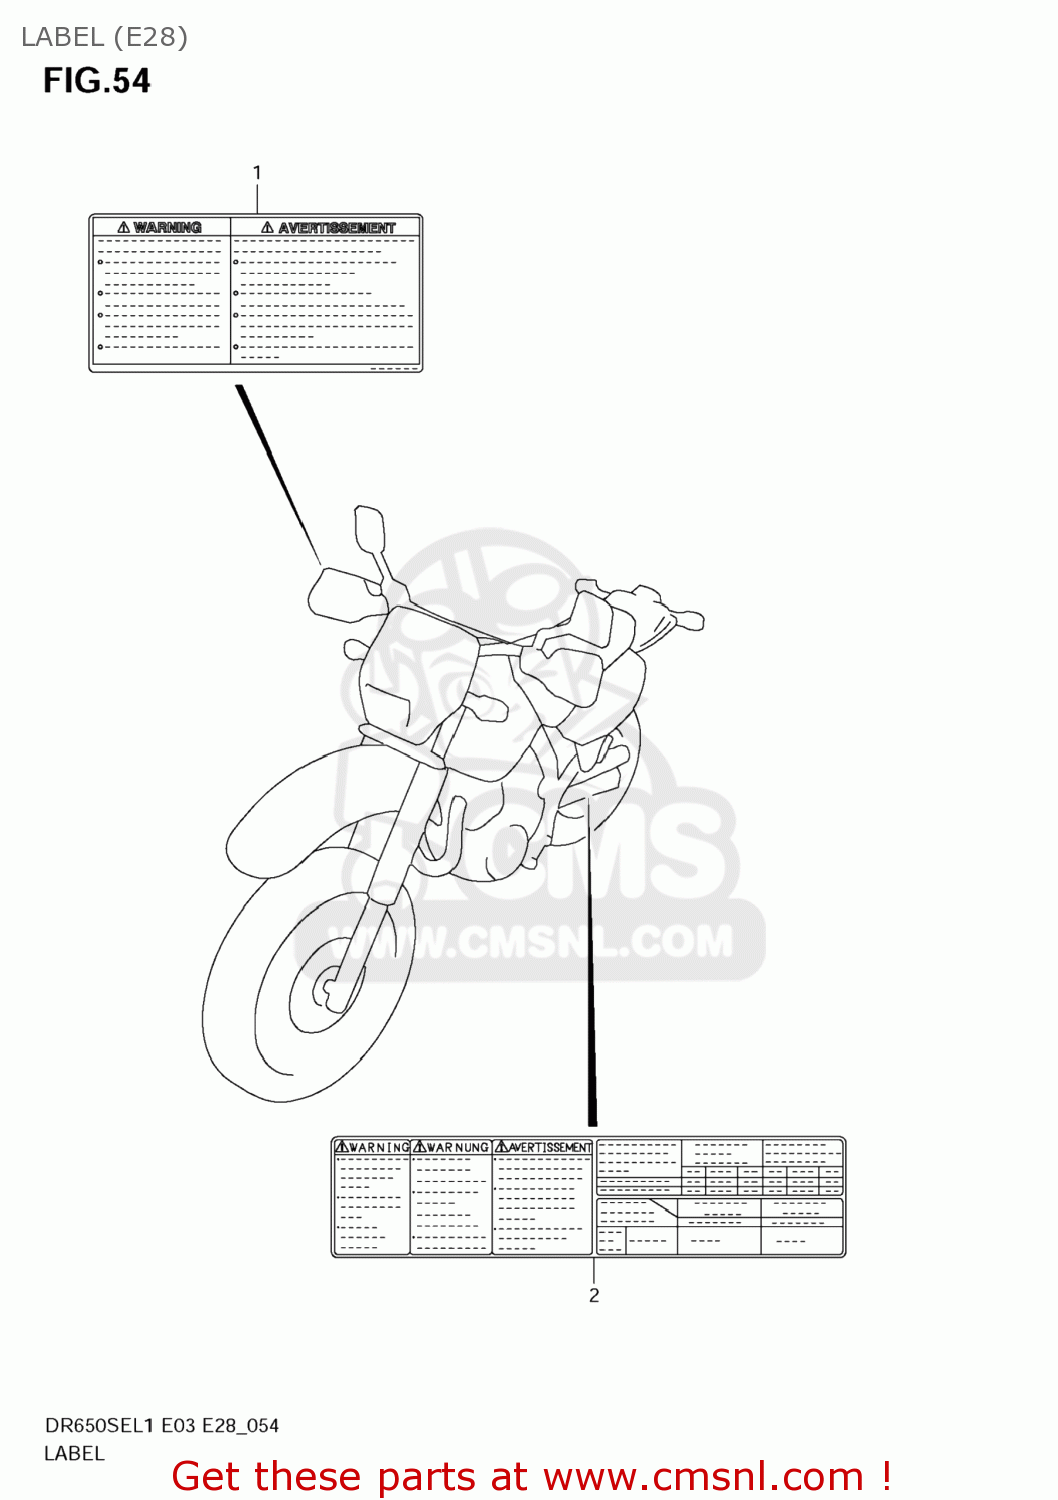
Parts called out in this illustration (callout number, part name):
1	LABEL,GENERAL WARNING
2	LABEL,TIRE INFORMATION
3	MANUAL,OWNER'S
